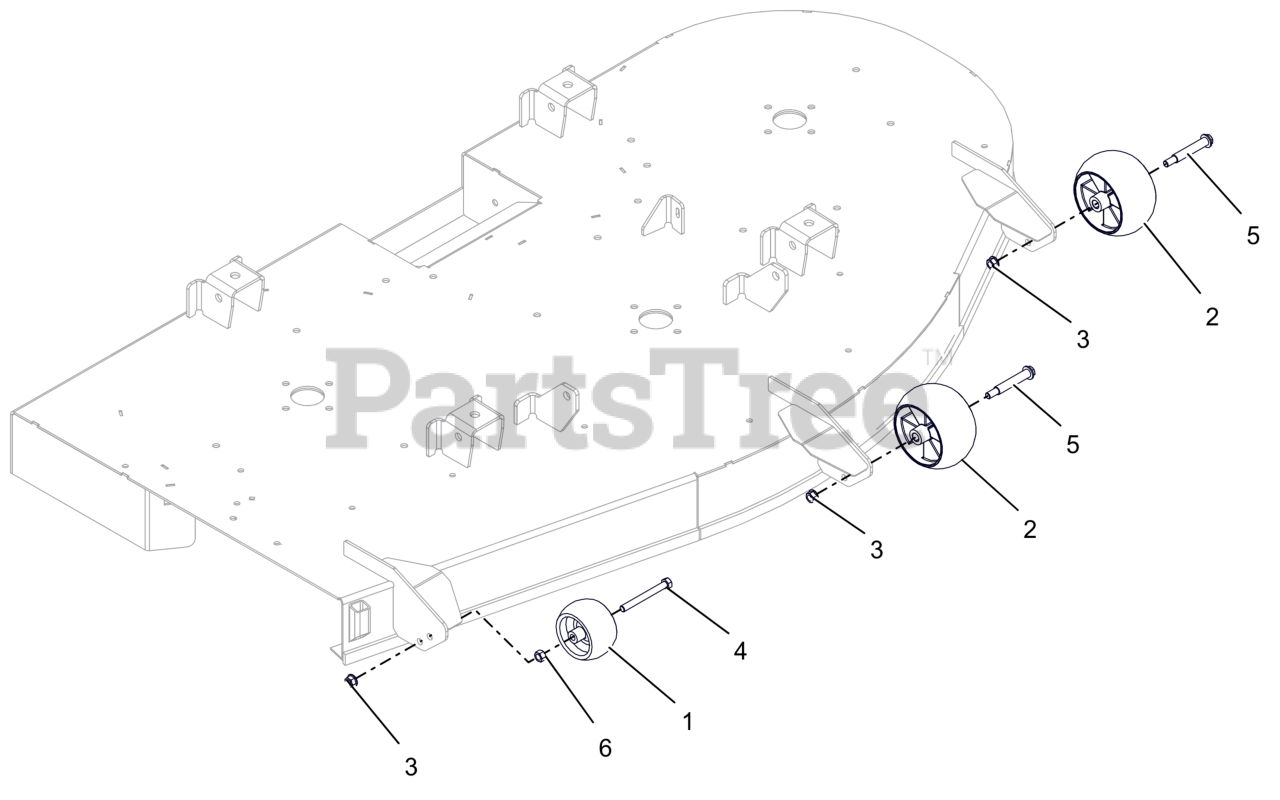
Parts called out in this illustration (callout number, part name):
2	ANTI-SCALP WHEEL - 5X OS
3	NUT-LK-CTR-FLG .375-16 GF ZCC
4	BLT, HEX .38-16X3.50 G5 ZCC
5	BLT-SHLDR .38-16X2.50 HWH G5
6	NUT-STD .375-16 G2 ZCC
